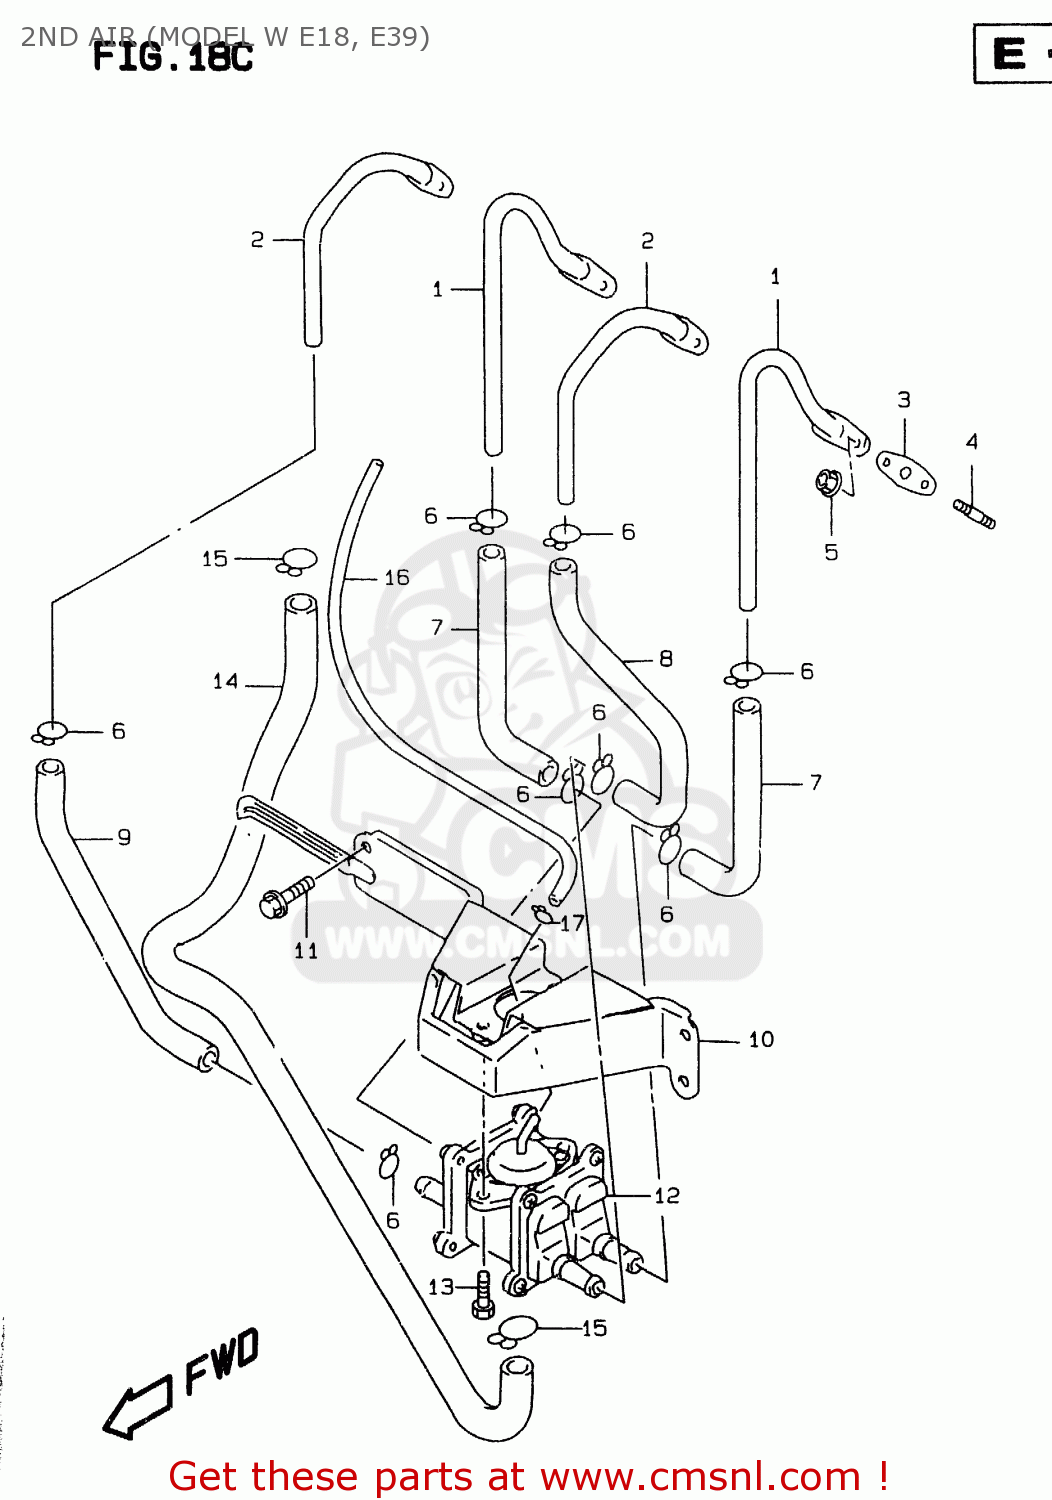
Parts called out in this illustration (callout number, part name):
1	PIPE COMP,SECOND AIR NO.1
2	PIPE COMP,SECOND AIR NO.2
3	GASKET,SECOND AIR PIPE (N (NAS)
4	STUD BOLT
5	NUT
6	CLIP
7	HOSE,2ND AIR VALVE NO.1
8	HOSE,2ND AIR VALVE NO.2
9	HOSE,2ND AIR VALVE NO.4
10	BRACKET,SECOND AIR VALVE
11	BOLT 6X12
12	VALVE ASSEMBLY,SECOND AIR
13	BOLT,OIL FILLE
14	HOSE,2ND AIR CLEANER
15	CLIP
16	HOSE(4X7X2000)
17	CLIP
